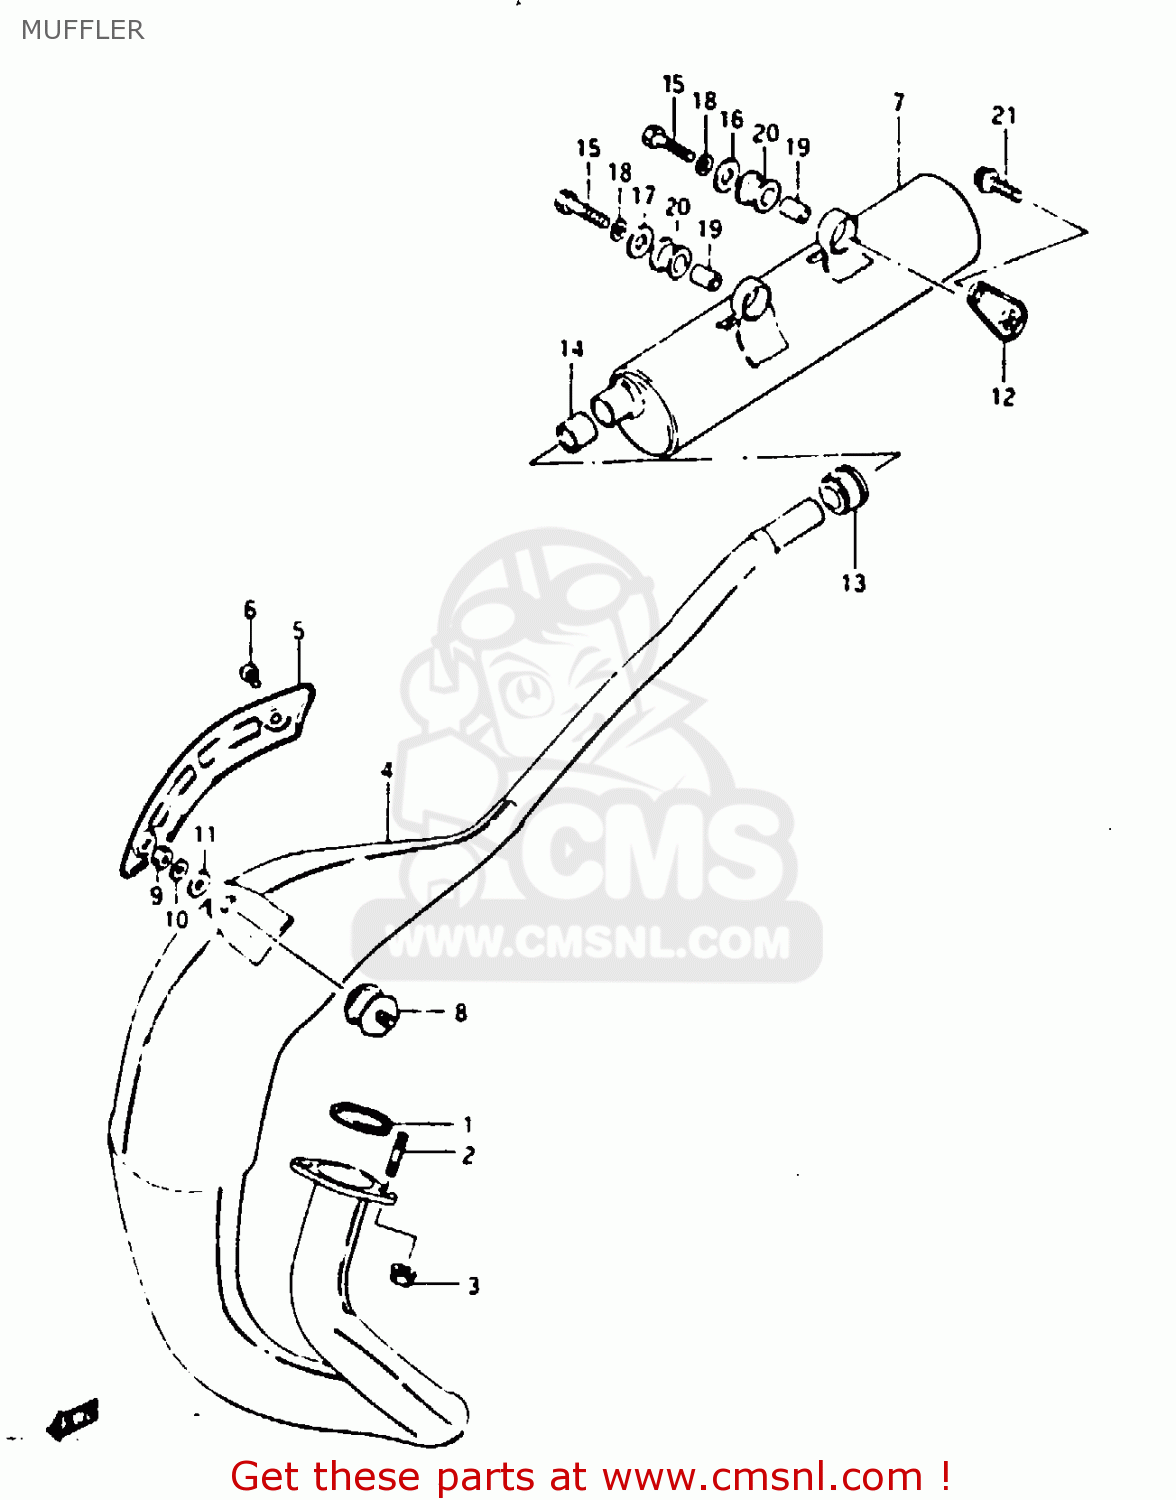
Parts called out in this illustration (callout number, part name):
1	GASKET,EXHAUST PIPE (NAS)
2	STUD BOLT
3	NUT
4	MUFFLER, 1ST
5	COVER,MUFFLER
6	SCREW
7	MUFFLER, 2ND
8	DAMPER,MUFFLER SUPPORT
9	NUT
10	LOCK WASHER
11	WASHER
12	BRACKET, 2ND MUFFLER
13	CONNECTOR,MUFFLER
14	CONNECTOR
15	BOLT
16	WASHER (8.5X20X1.6)
17	WASHER
18	WASHER,LOCK,8.
19	SPACER (8.6X12X17.5)
20	CUSHION
21	BOLT
